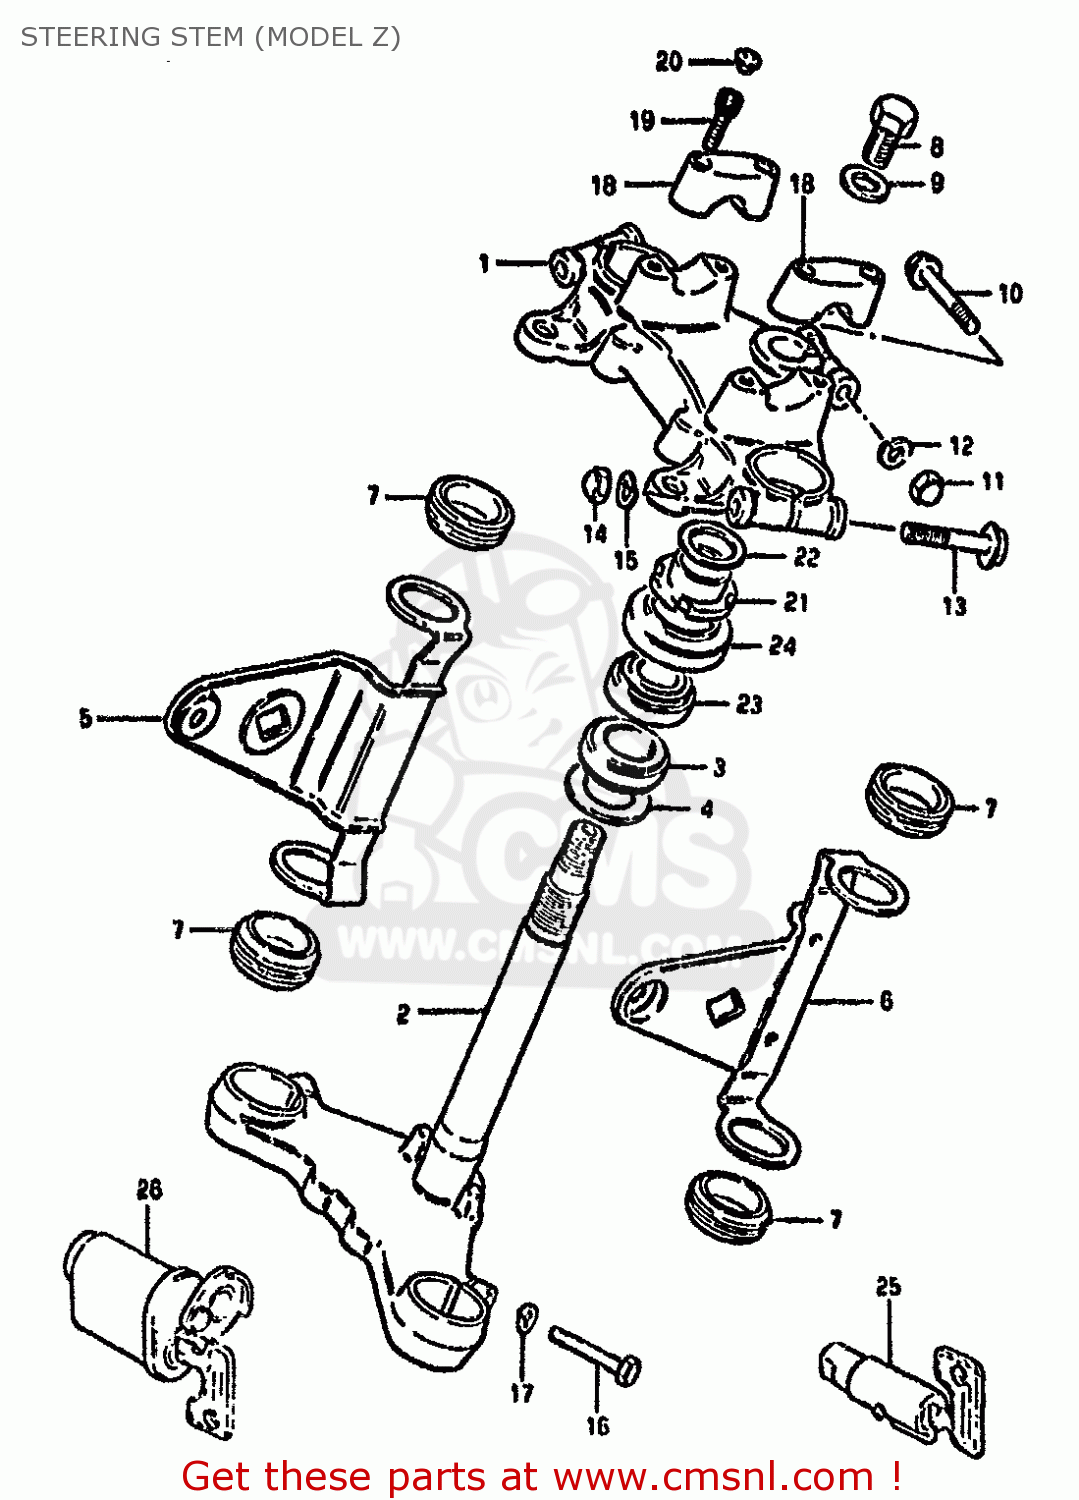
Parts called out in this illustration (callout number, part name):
1	HEAD,STEERING STEM
2	STEM,STEERING
3	BEARING
4	WASHER,THRUST
5	BRACKET,HEADLAMP,RIGHT
6	BRACKET,HEADLAMP,LEFT
7	CUSHION,HEADLAMP BRACKET
8	BOLT 12X20
9	WASHER (12.5X26X1.6)
10	BOLT
11	NUT,M8X1.25X12
12	LOCK WASHER
13	BOLT 10X55
14	NUT
15	LOCK WASHER
16	BOLT 10X40
17	LOCK WASHER
18	HOLDER,HANDLEBAR(BLACK)
19	BOLT
20	CAP(OD:14.5)
21	NUT,STEERING STEM
22	WASHER(18.5X24X1)
23	TAPER,ROLLER BEARING
24	DUST SEAL,STEERING UPR
25	LOCK ASSEMBLY,STEERING (NEI
26	LOCK ASSY, STEERING (NEIMAN TYPE EXECUTE
